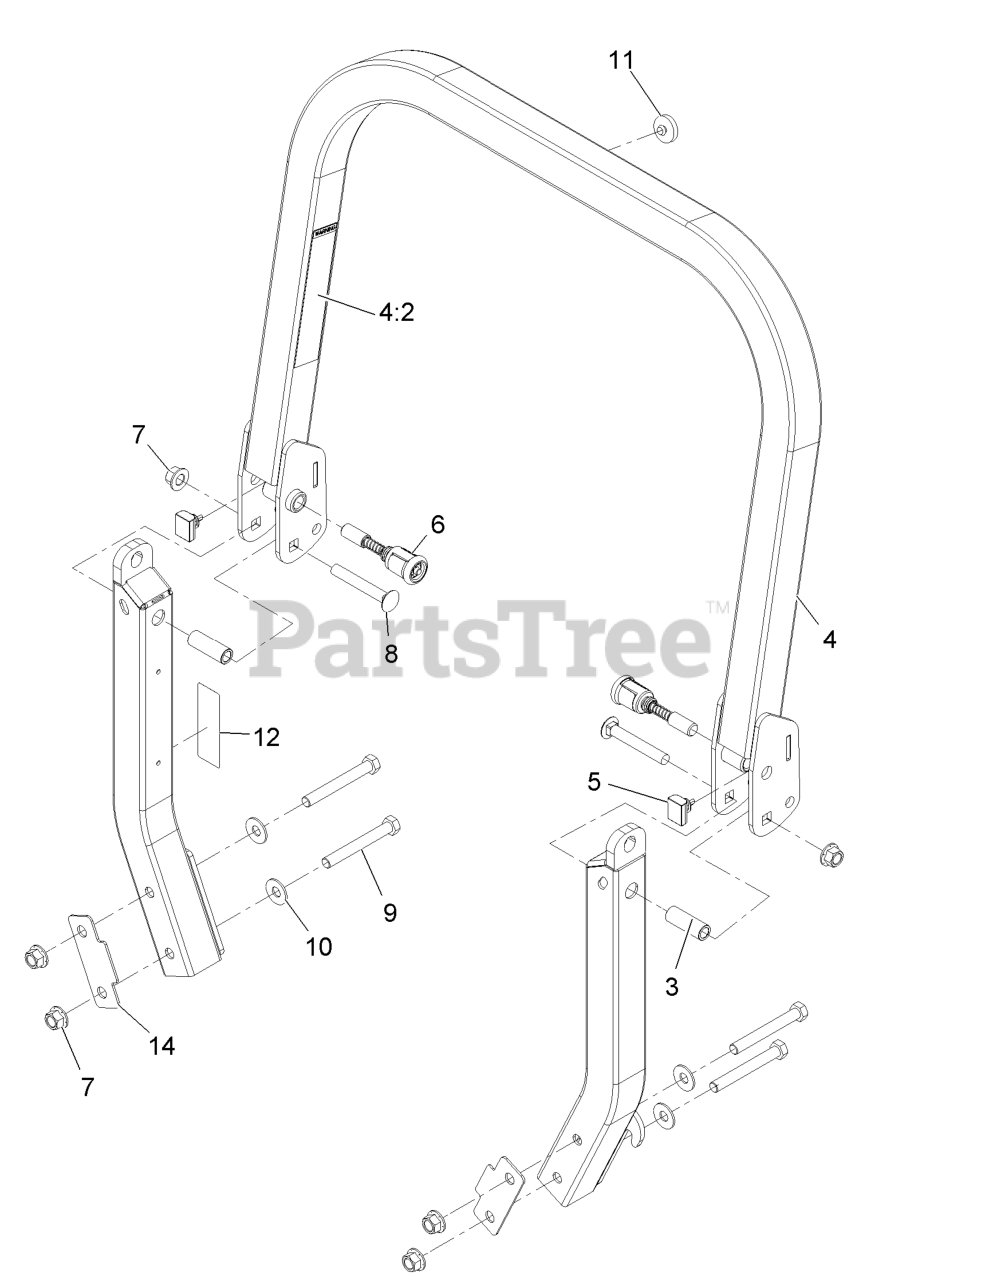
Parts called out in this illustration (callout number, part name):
4	UPPER ROPS ASM
4:2	DECAL-WARNING, FOLDING RO
5	BUMPER-ROPS
6	PIN-SPRING
7	Nut-Lock 1/2-13
8	SCREW-CARR
9	SCREW-HH
10	WASHER-SPRING
11	BUMPER-PUSH-IN, RUBBER
12	DECAL-CAUTION
